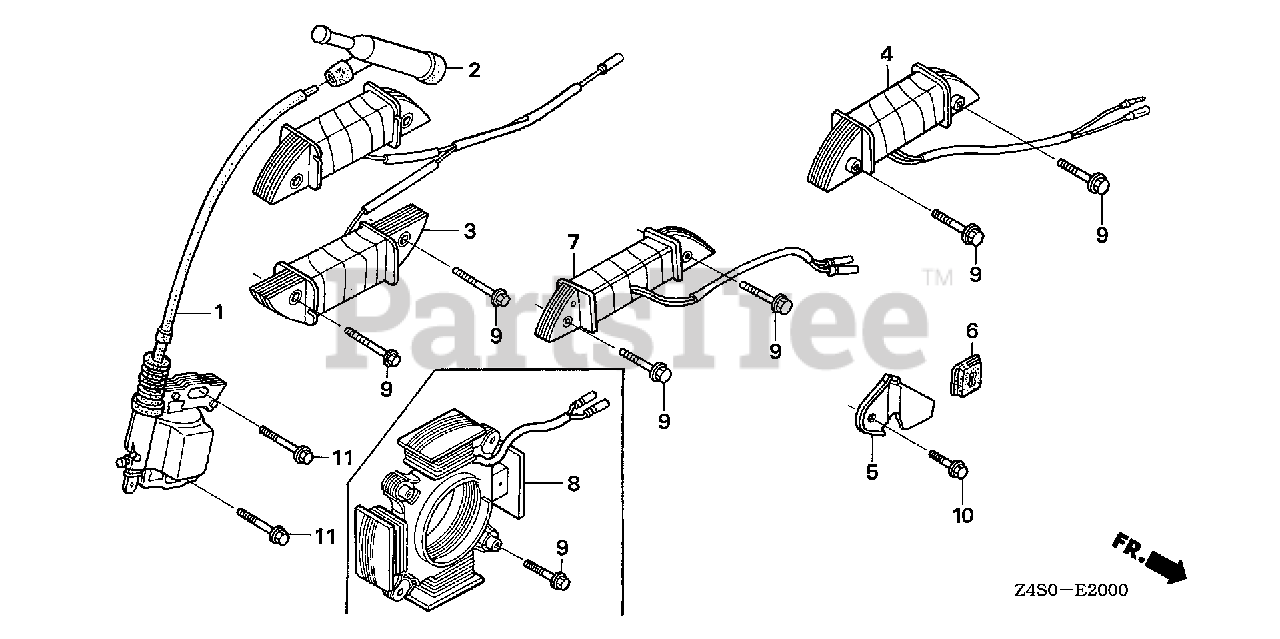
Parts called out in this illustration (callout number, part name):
1	COIL ASSY., IGNITION
2	CAP ASSY., NOISE SUPPRESSOR (NICHIWA Y-EZ RTFM256)
11	BOLT, FLANGE (6X25) (CT200)
